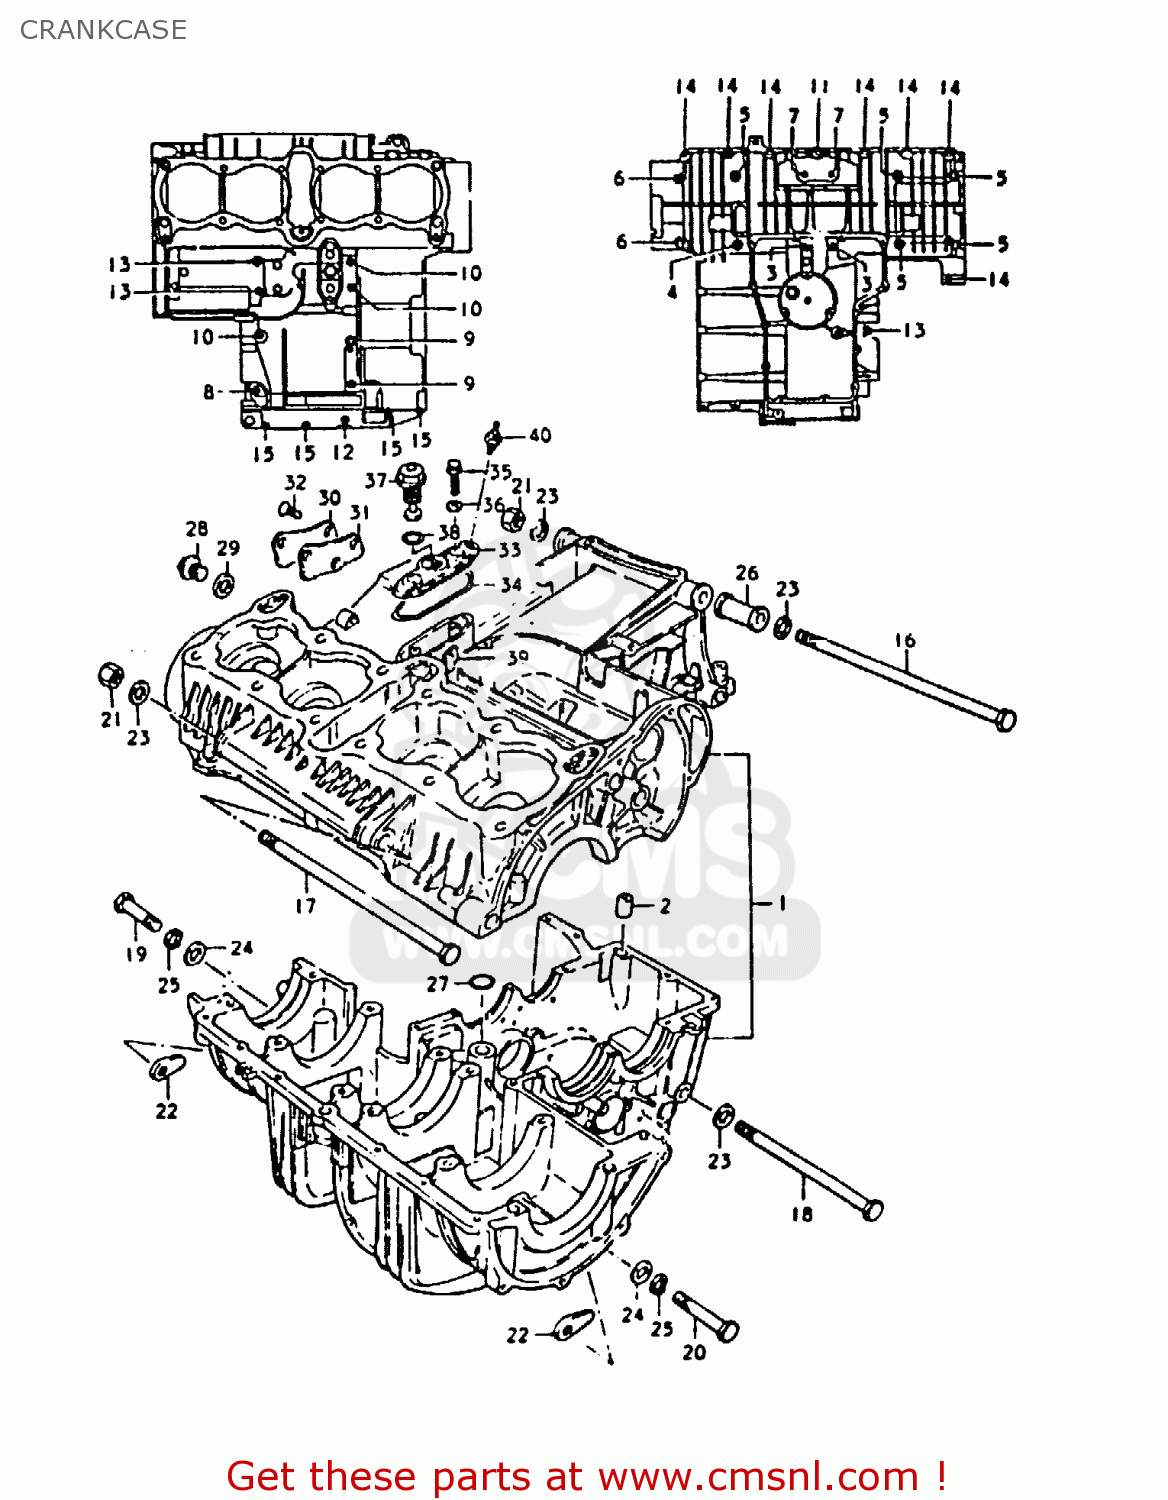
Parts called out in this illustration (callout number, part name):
1	CRANKCASE SET
2	PIN
3	BOLT
4	BOLT
5	BOLT 8X90
6	BOLT 8X65
7	BOLT
8	BOLT
9	BOLT
10	BOLT (6X75)
11	BOLT ,6X50
12	BOLT,UNDER
13	BOLT
14	BOLT 6X35
15	BOLT
16	BOLT 10X265
17	BOLT 10X250
18	BOLT(10X165)
19	BOLT 10X60
20	BOLT (10X50)
21	NUT
22	NUT
23	WASHER
24	WASHER(10.5X20X3.2)
25	LOCK WASHER
26	SPACER,ENGINE MOUNT
27	O RING(D:3.2,ID:12.9)
28	PLUG (14X12)
29	GASKET(14X19.2X2) (NAS)
30	CAP,OIL GALLERY
31	GASKET,OIL GALLERY (MCA)
32	SCREW
33	HOUSING,OIL PRESSURE SWITCH
34	O RING,PRESSURE SWITCH HOUSING
35	BOLT
36	GASKET (NAS)
37	SWITCH ASSEMBLY
38	O RING(D:1.9,ID:18.8)
39	GROMMET,STARTING MOTOR
40	GAUGE ASSEMBLY,OIL TEMPERATURE
